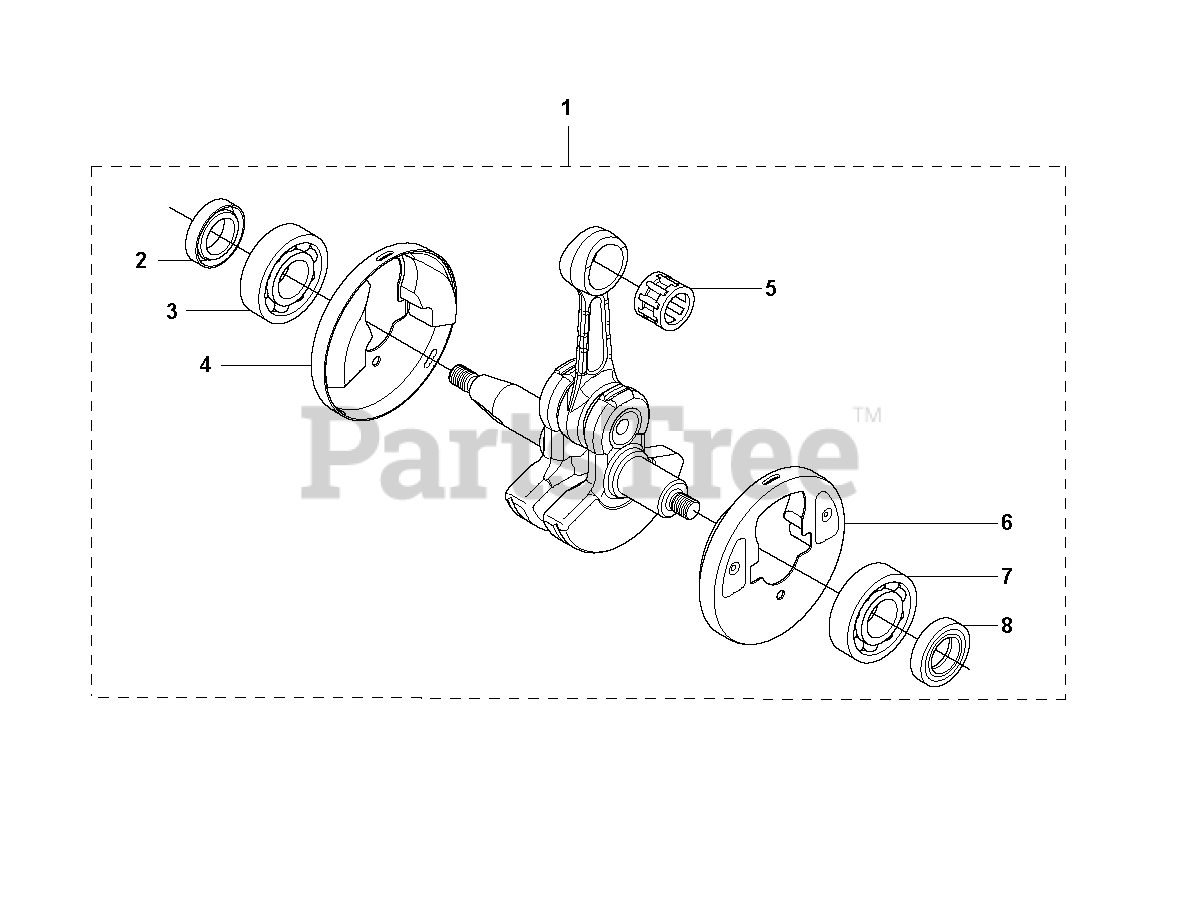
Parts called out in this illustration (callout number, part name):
1	CRANKSHAFT
2	SEALING RING
3	BALL BEARING
4	COLLAR
5	SUPPORT BUSHING
6	COLLAR
7	BALL BEARING
8	SEALING RING
